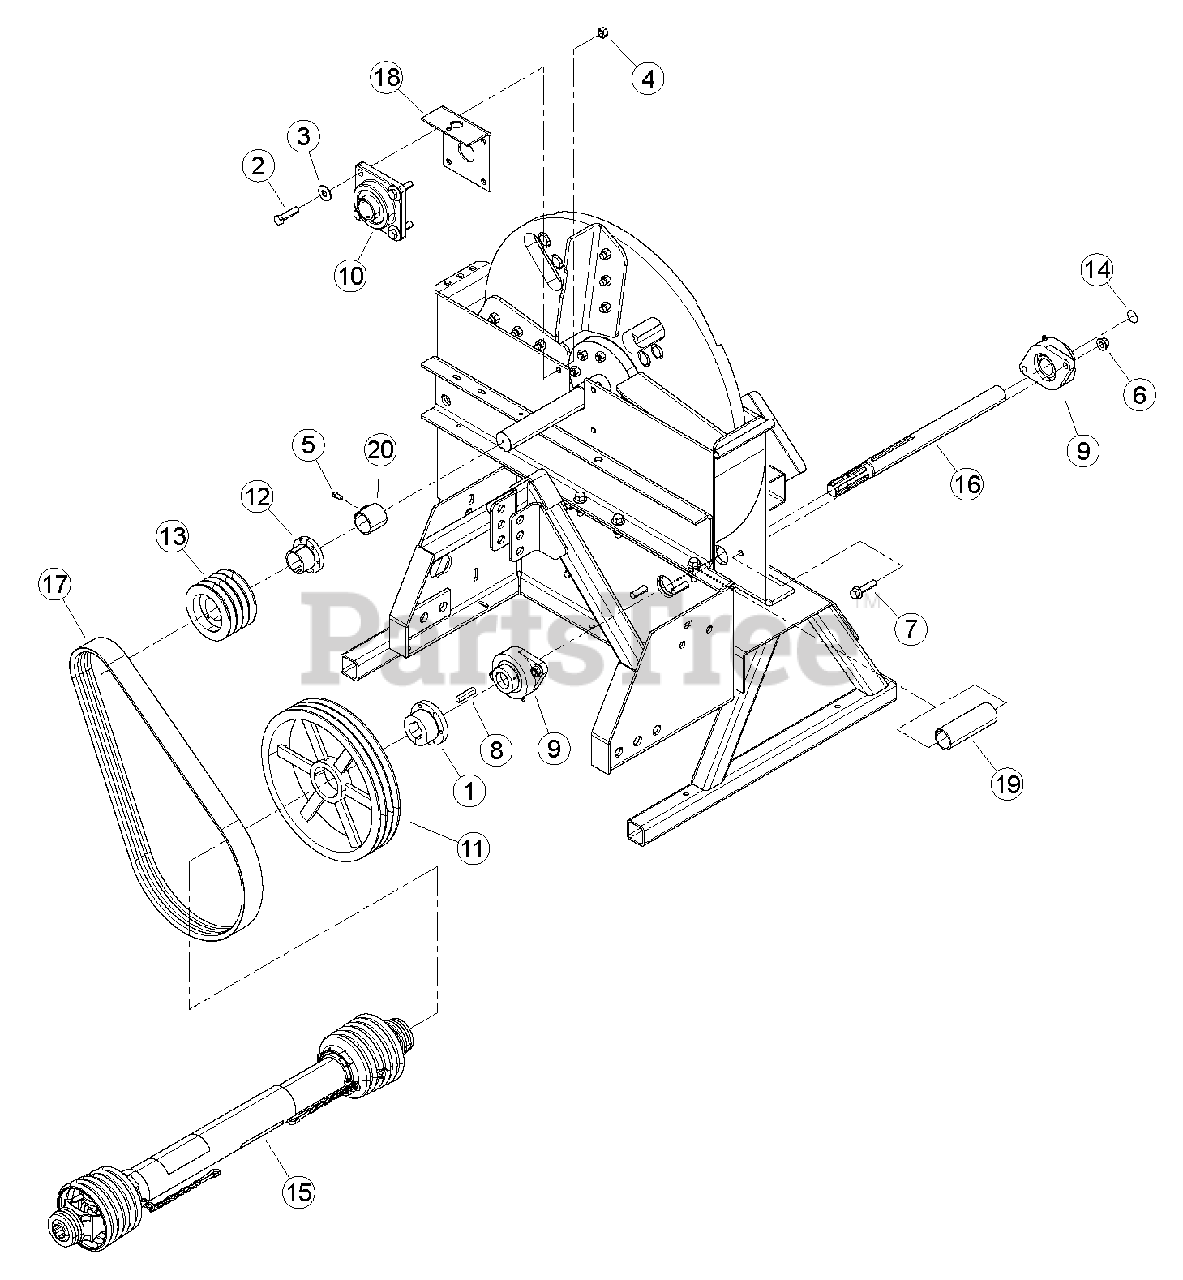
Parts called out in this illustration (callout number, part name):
1	BUSHING, SK 1-1/2"
2	BOLT, 1/2-13 X 2 GR5 HEX CAPSCREW
3	WASHER, 1/2 FLAT
4	NUT, 1/2-13 GR5 CENTERLOCK GRB
5	SCREW, 5/16-18 X 5/8 SQ HD SET
6	NUT, 1/2-13 NYLOCK FLANGE
7	BOLT, 1/2-13 X 2 HWH GR5 CZP
8	KEY, 3/8" SQ X 2" LG PLAIN
9	BEARING, 2 BOLT FLANGE 1-1/2" BORE
10	BEARING, 1-3/4 4 BOLT FLANGE
11	SHEAVE, 3B13.6 SK
12	BUSHING, SD 1-3/4"
13	SHEAVE, 4BQ4.8 SD
14	DECAL, ROTATING SHAFT
15	DRIVELINE, 33.9/47.6" 1-3/8 SPL CE
16	SHAFT, 6 SPLINE INPUT
17	BELT, 3RB64
18	WELDMENT, LEFT BEARING BRACKET
19	SHIELD, SHAFT
20	WELDMENT, SPACER
